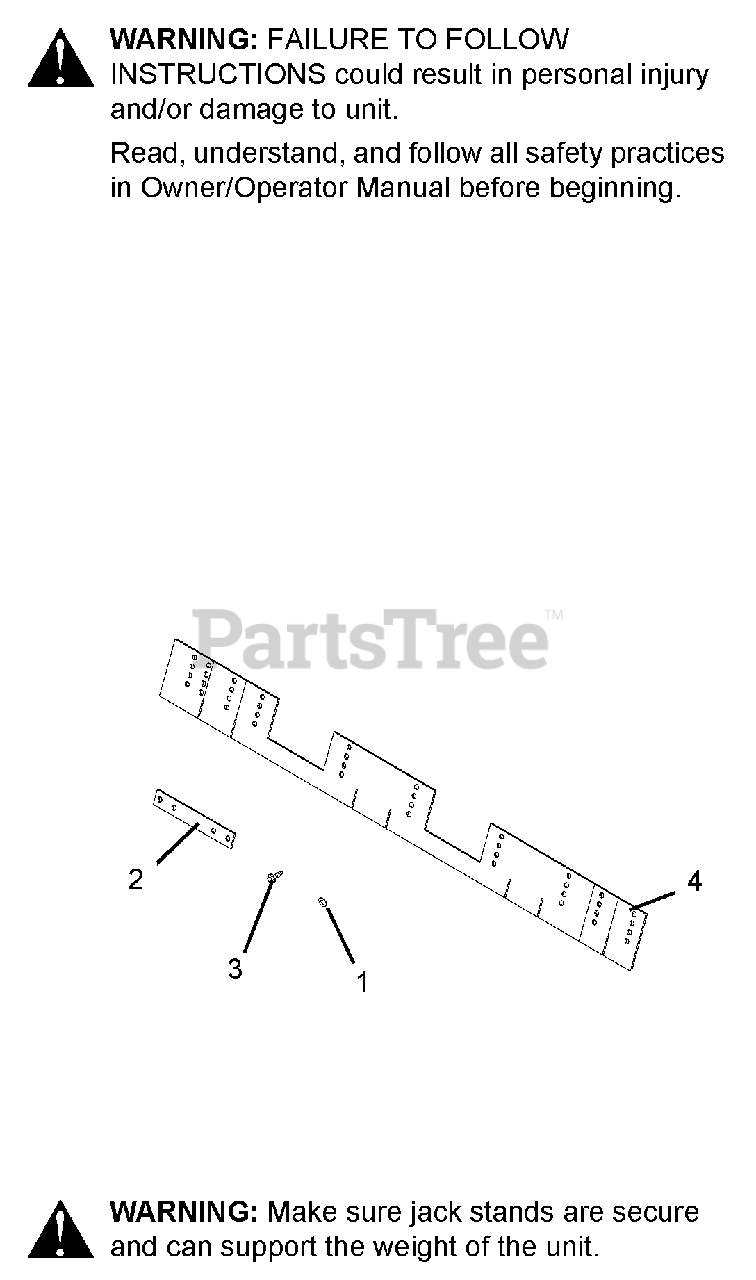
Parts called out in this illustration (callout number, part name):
1	WSHR-FL-STL .406X1.375X.135 YZ
2	BAR, STRIPER
3	@SCR-TAP .38-16X.75 HWH TR YWZ
4	SKIRT,100SERIES RUBBER STRIPER
